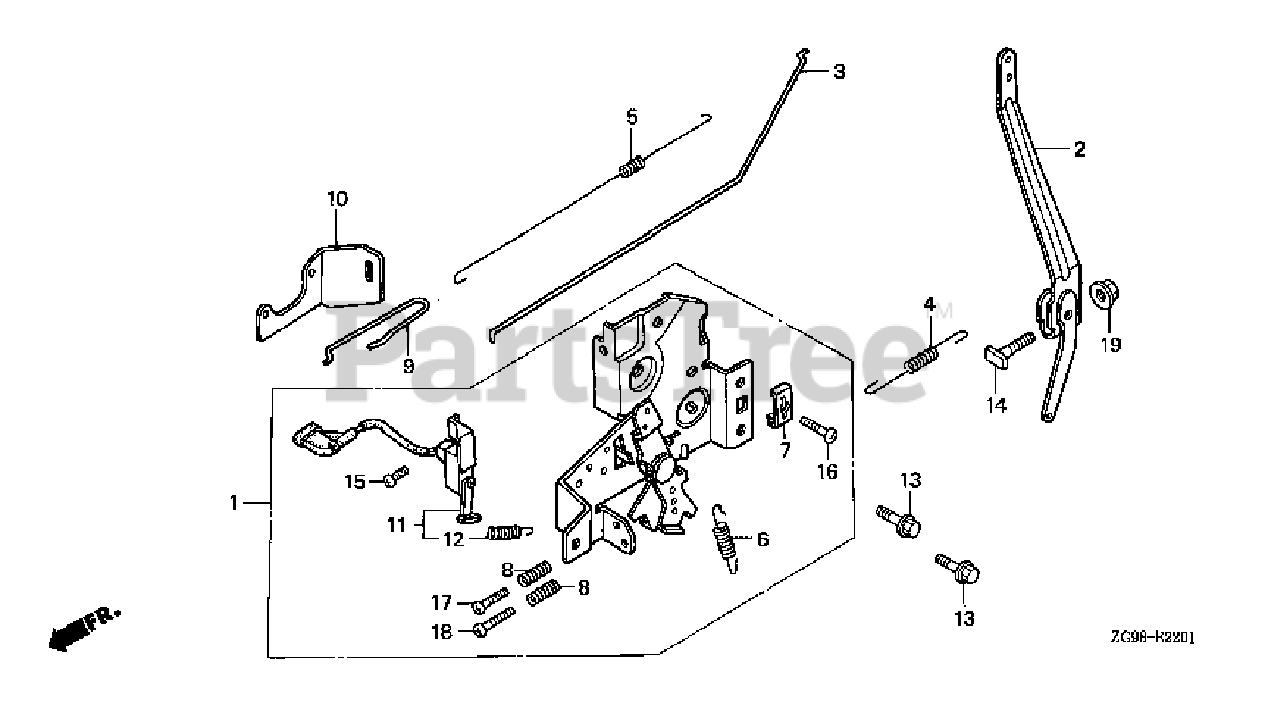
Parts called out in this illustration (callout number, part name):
1	CONTROL ASSY.
2	ARM, GOVERNOR
3	ROD, GOVERNOR
4	SPRING, GOVERNOR
5	SPRING, THROTTLE RETURN
6	SPRING, LEVER
7	HOLDER, CABLE
8	SPRING, CONTROL ADJUSTING
9	ROD, CHOKE CONTROL
10	BRKT, CHOKE LEVER
11	SWITCH ASSY., ENGINE STOP
12	SPRING, SWITCH CONTROL
13	BOLT, FLANGE (6X14)
14	BOLT, GOVERNOR ARM
15	SCREW, PAN (4X8)
16	SCREW, PAN (5X16)
17	SCREW, PAN (5X20)
18	SCREW, PAN (5X25)
19	NUT, FLANGE (6MM)
